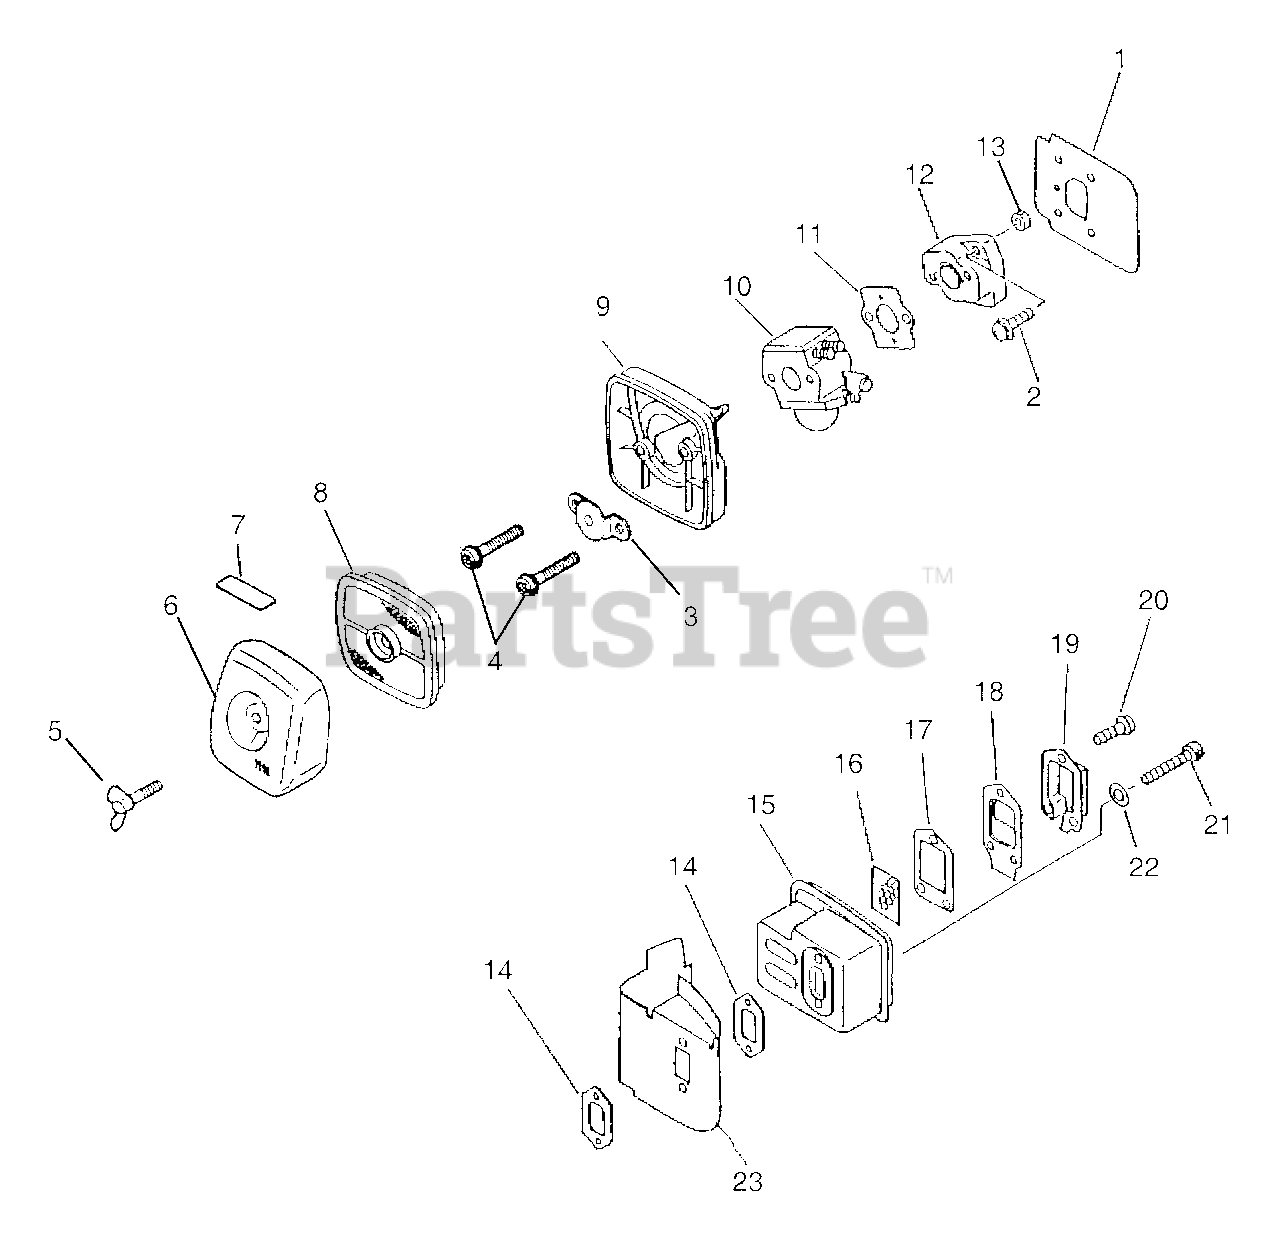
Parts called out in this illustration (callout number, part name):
1	SHIELD, INTAKE
2	SCREW - 5X20
3	PLATE, PREVENT
4	SCREW - 5X65
5	THUMBSCREW
6	COVER, AIR FILTER - GRAY
7	LABEL - CHOKE
8	FILTER, AIR
8	FILTER, AIR - SINGLE LAYER
9	AIR FILTER CASE ASSY
10	CARBURETOR C1U-K51
11	GASKET, INTAKE
12	INSULATOR, INTAKE
14	GASKET, EXHAUST
16	SCREEN, SPARK ARRESTOR
17	GASKET, EXHAUST
18	GASKET, EXHAUST - INNER
19	GUIDE, EXHAUST - OUTER
20	SCREW - 4X10
21	SCREW - 5X55
22	WASHER - 5
23	COVER, EXHAUST
